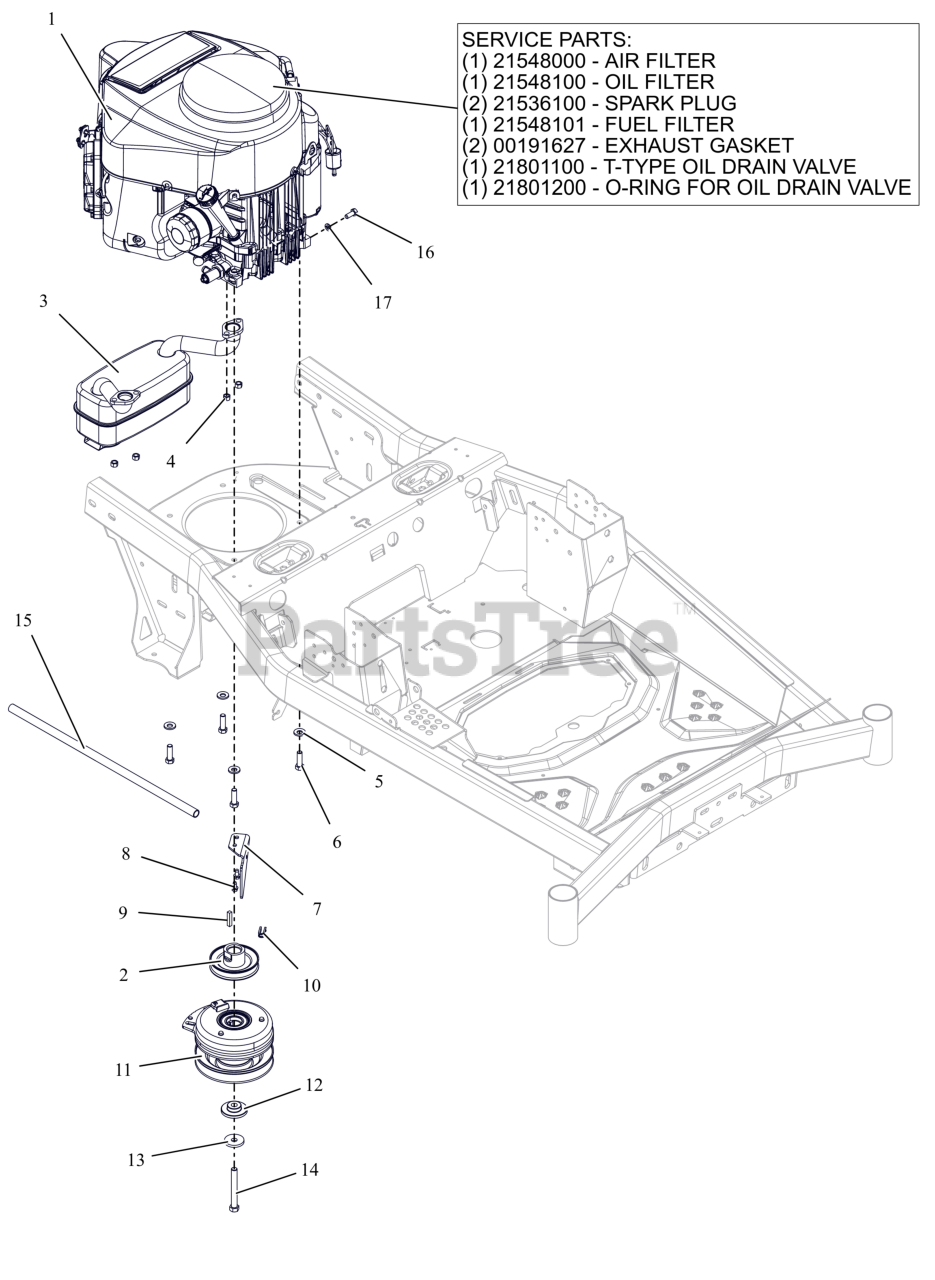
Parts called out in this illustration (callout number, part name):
1	ENGINE, KAWASAKI FR691 23HP
1	AIR FILTER, KAWASAKI FR
1	OIL FILTER, KAWASAKI FR
1	PLUG, SPARK
1	FUEL FILTER-KAWASAKI FR
1	GASKET, MUFFLER S/O
1	T-TYPE OIL DRAIN VALVE
1	O-RING FOR OIL DRAIN VALVE
2	WLDMT, PULLEY 3.75 OD X 1.003 ENGINE
3	MUFFLER - KAWASAKI
4	NUT-LK-TOP-FLG M8 ZCC
5	WASHER, 3/8" SPRING DISC
6	BLT, HEX .38-16X1.25 G5 ZCC NT
7	BRKT- CLUTCH STOP
8	SCR-TAP .25-20X.50 HWH ZCC
9	KEY-SQ .25 X 1.25 X .25 SAE
10	BSHG, CLUTCH
11	CLUTCH- WARNER IXR-18211
12	BSHG-FLG .469X1.06X.574X2.0
13	WASHER, 7/16" SPRING DISK
14	BLT, HEX 0.4375-20X3.5 G8 ZCC NT
15	HOSE, OIL DRAIN
16	BLT, HEX M8-1.25X20 G8.8 ZCC
17	WSHR,LK-REG .312X.078 ZCC
